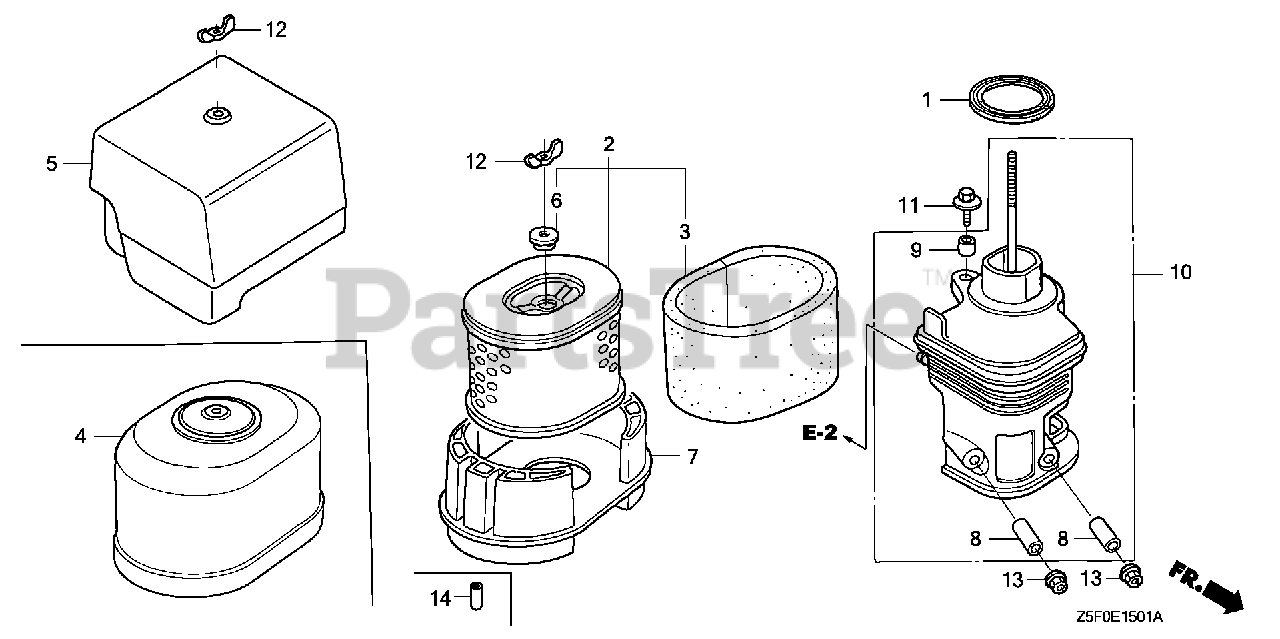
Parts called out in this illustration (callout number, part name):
1	GASKET, ELBOW
2	ELEMENT, AIR CLEANER (DUAL)
3	FILTER (OUTER)
5	COVER, AIR CLEANER
6	GROMMET, AIR CLEANER
7	NOSE, MUFFLER
8	COLLAR, AIR CLEANER
9	COLLAR B, AIR CLEANER
10	ELBOW, AIR CLEANER
10	ELBOW COMP, AIR/C
11	BOLT-WASHER (6X22)
12	NUT, TOOL BOX SETTING
13	NUT, FLANGE (6MM)
14	CAP, SEALING
